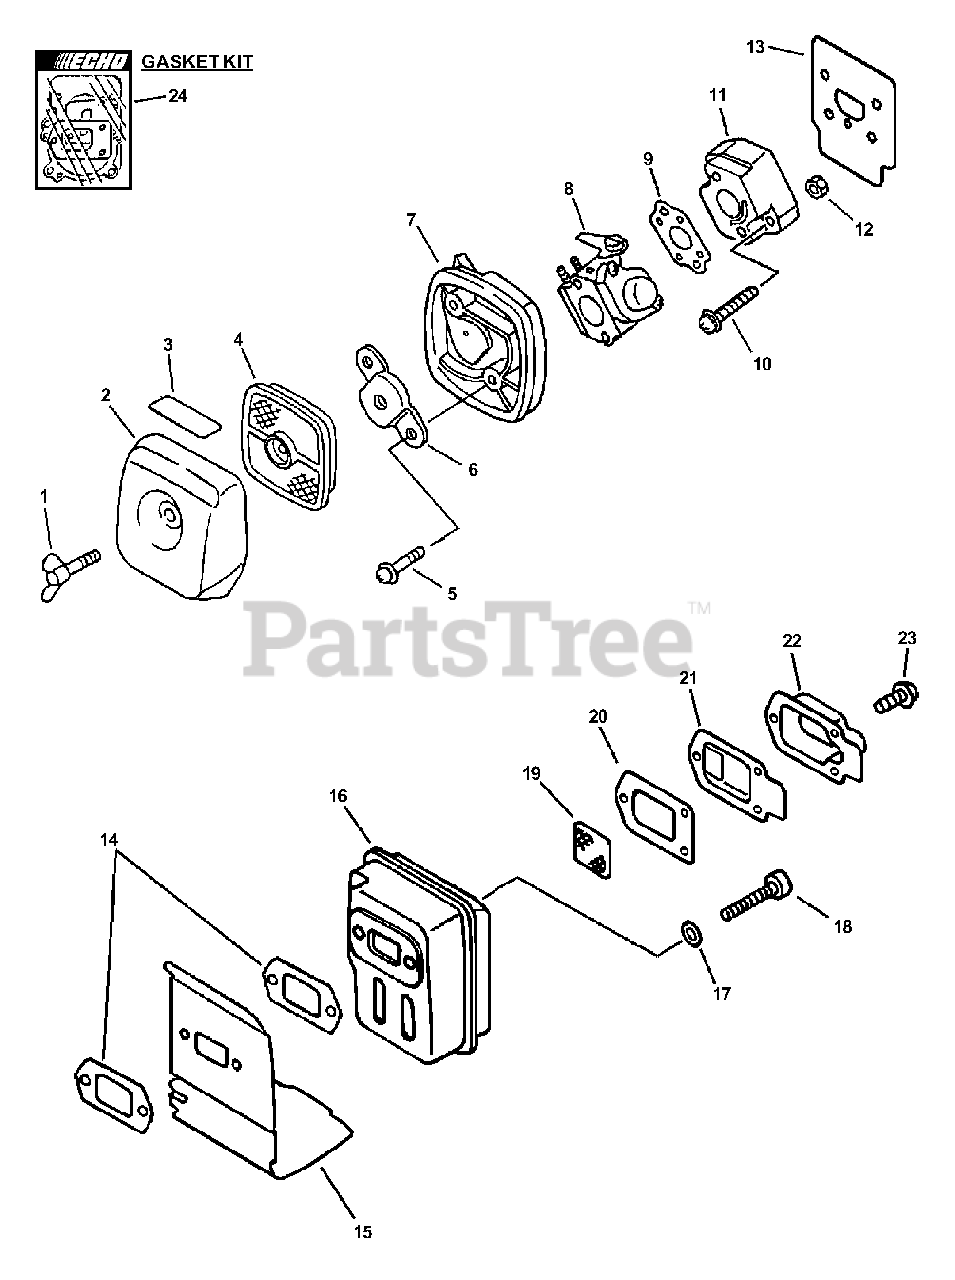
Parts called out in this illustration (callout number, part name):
1	THUMBSCREW
2	COVER, AIR FILTER - GRAY
3	LABEL - CHOKE
4	FILTER, AIR - SINGLE LAYER
5	SCREW - 5X65
6	PLATE, PREVENT
7	AIR FILTER CASE ASSY
8	CARBURETOR C1U-K52
9	GASKET, INTAKE
10	SCREW - 5X20
11	INSULATOR, INTAKE
13	SHIELD, INTAKE
14	GASKET, EXHAUST
15	COVER, MUFFLER
17	WASHER - 5
18	SCREW - 5X55
19	SCREEN, SPARK ARRESTOR
20	GASKET, EXHAUST
21	GASKET, EXHAUST - INNER
22	GUIDE, EXHAUST - OUTER
23	SCREW - 4X10
24	GASKET KIT
